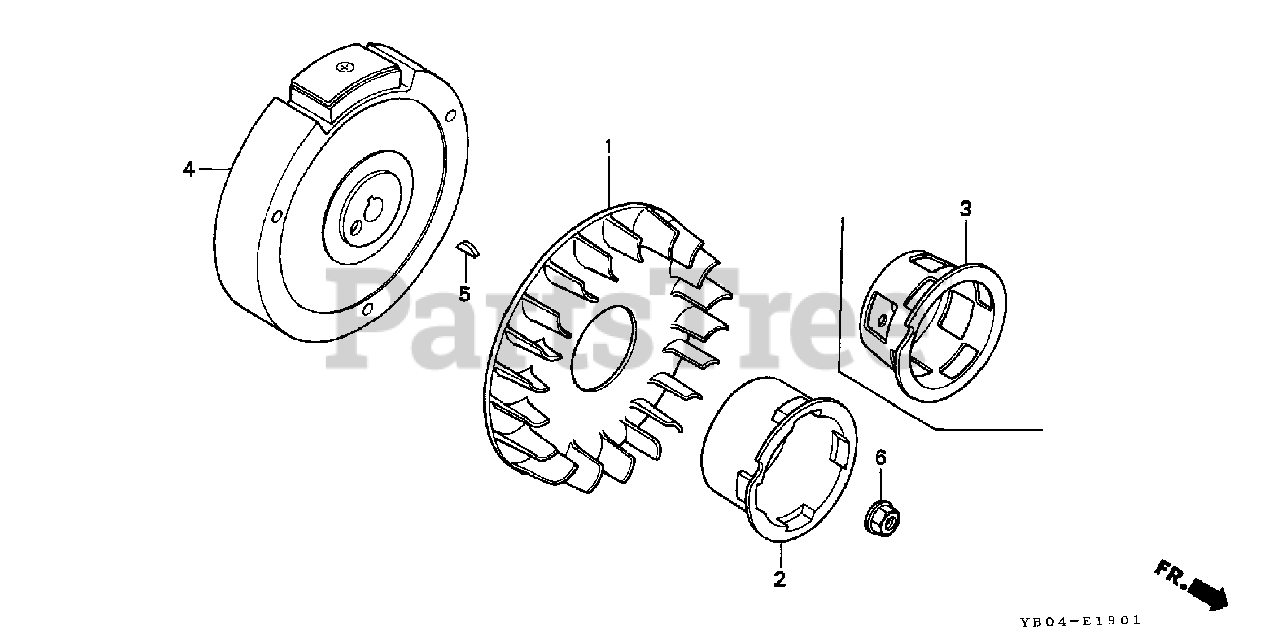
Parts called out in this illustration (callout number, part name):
1	FAN, COOLING
2	PULLEY, STARTER
4	FLYWHEEL
5	KEY, WOODRUFF (3MM)
6	NUT, FLANGE (12MM)
